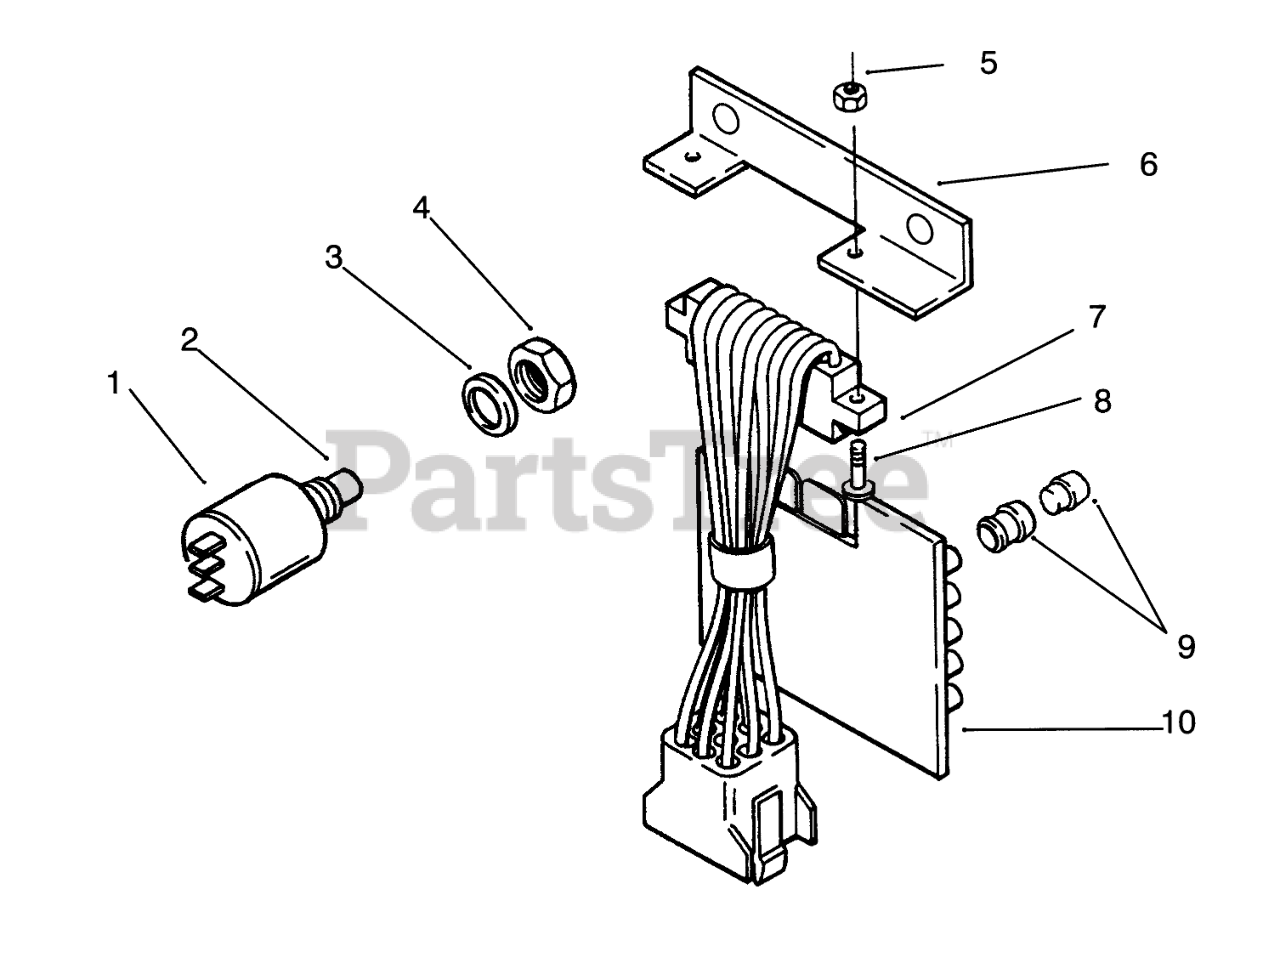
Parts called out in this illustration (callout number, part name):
1	Test Switch(Incl. Ref. #2-4)
2	BUTTON F/W 116796
3	Washer
4	NUT F/W 116796
5	Nut-Lock
6	BRACKET
7	P.C. BOARD HARNESS
8	Screw
9	ASSY LENS & BUSHING
10	Board-Pc
